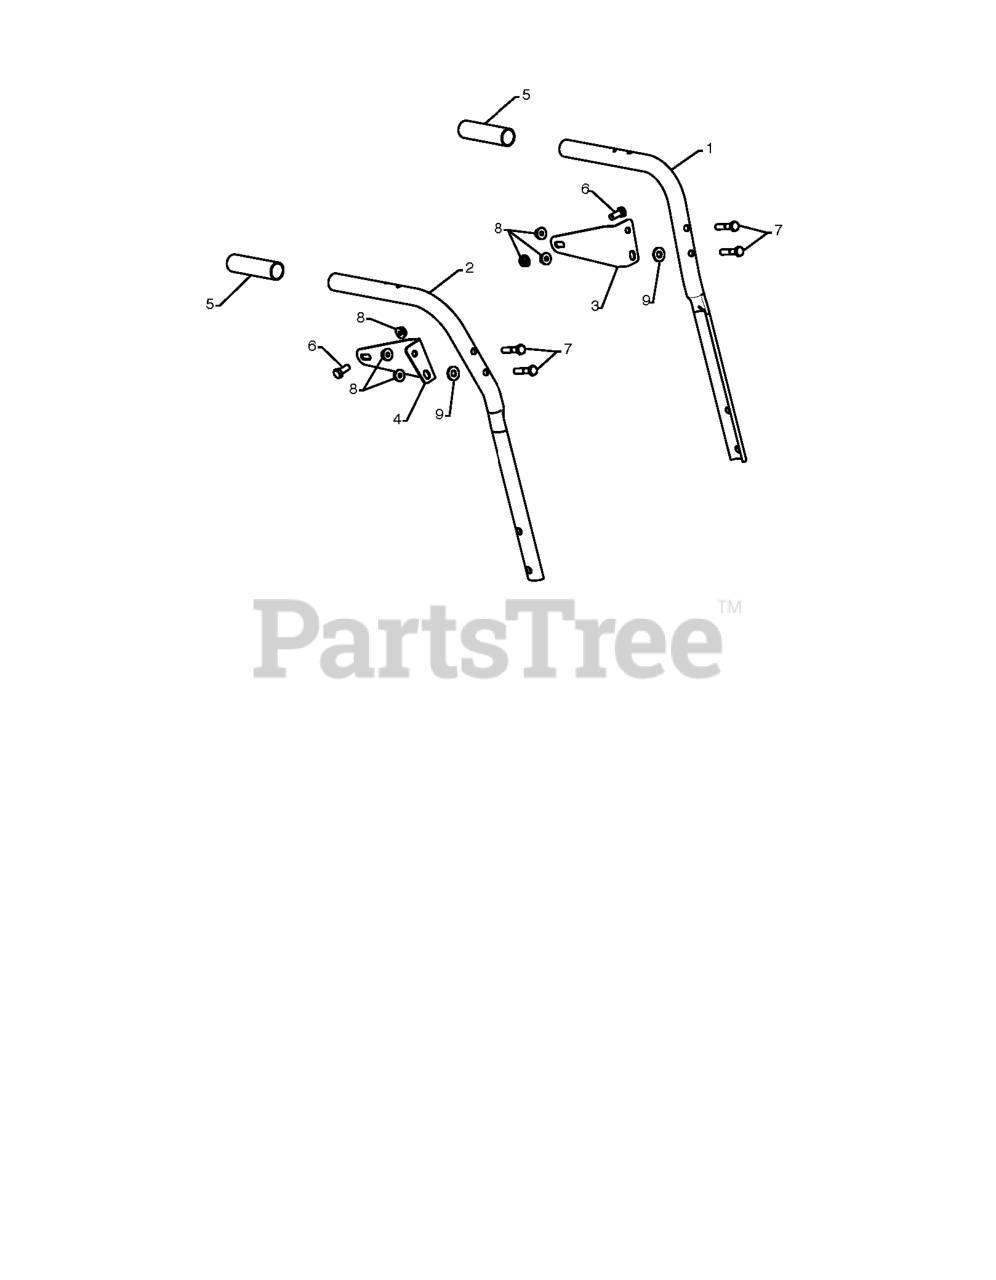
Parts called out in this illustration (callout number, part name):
1	TUBE.HANDLE.PLOW.LH.GREY
2	TUBE.HANDLE.PLOW.RH.GREY
3	BRACKET.PANEL.LH.
4	BRACKET.PANEL.RH
5	GRIP, HANDLE
6	BOLT.FIN.HEX.5/16-18X3/4
7	HEX BOLT
8	NUT.LOCK.5/16-18
9	WASHER.20X8.5
